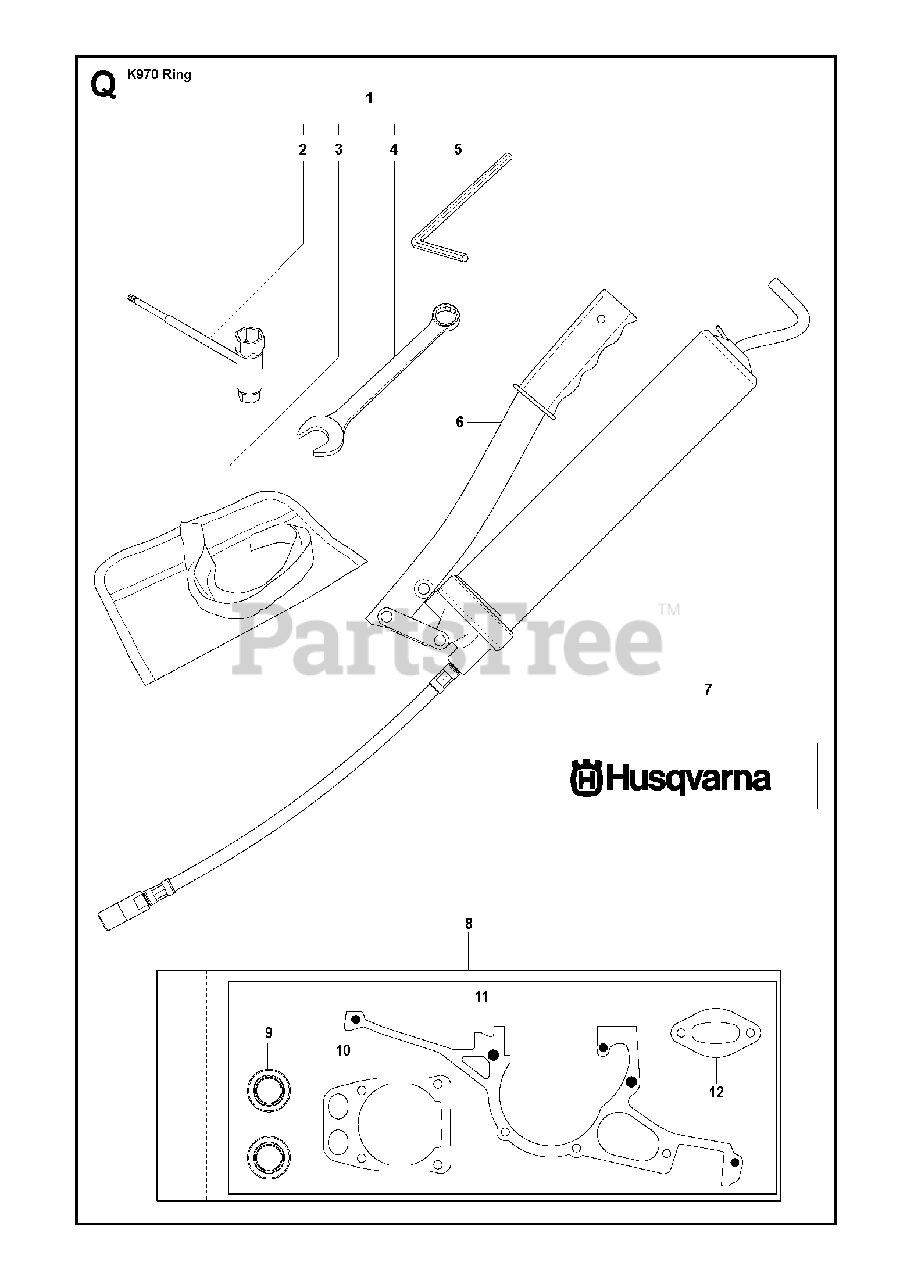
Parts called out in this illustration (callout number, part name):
7	GREASE
8	GASKET KITIncl. 9 - 12
9	SEALING RING
12	GASKET
